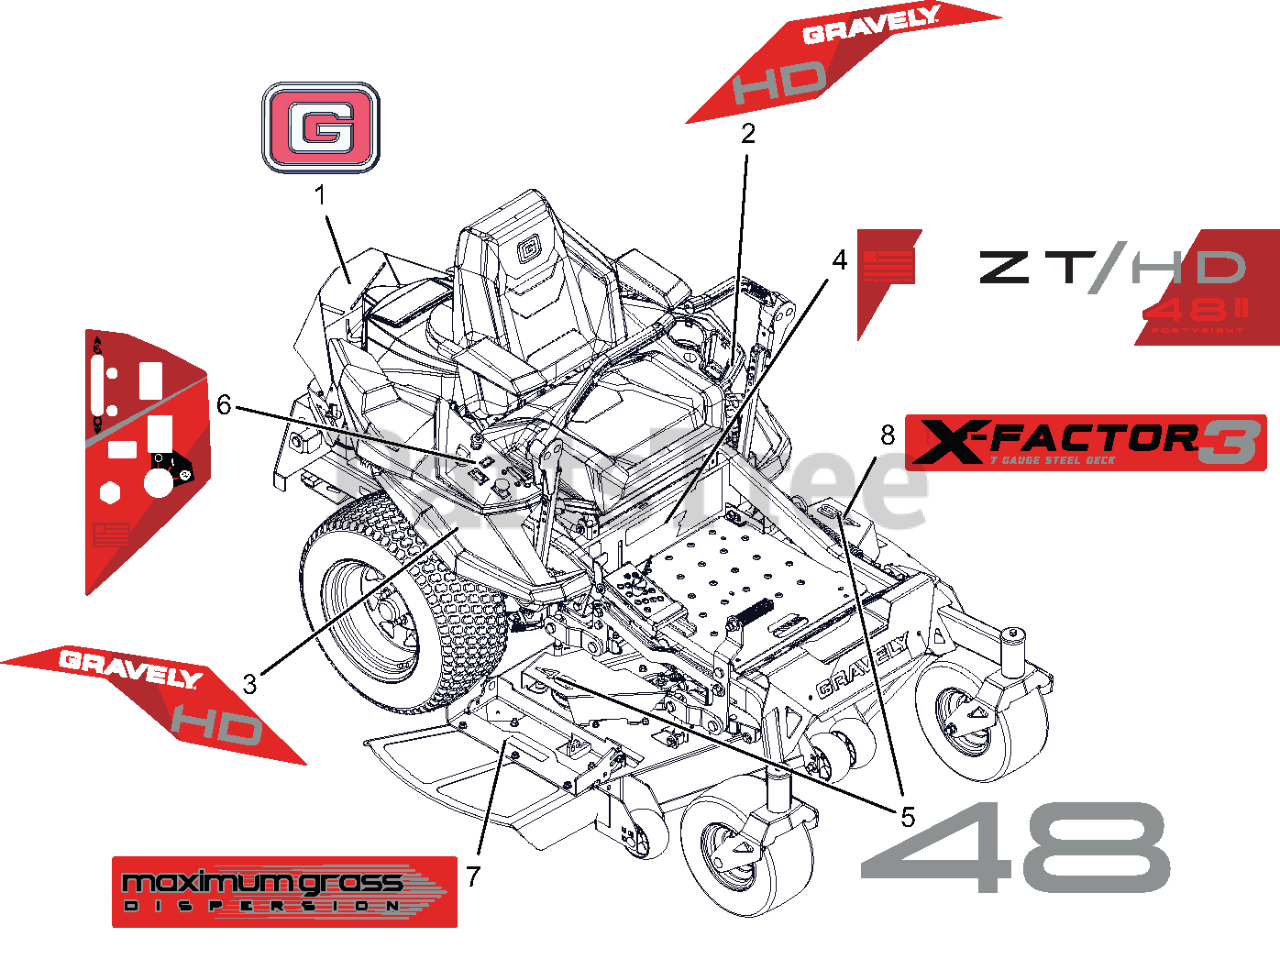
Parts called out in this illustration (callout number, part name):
1	DECAL, GRAVELY BRAND
2	DECAL, FENDER LH - HD
3	DECAL, FENDER RH - HD
4	DECAL, ZT/HD - 48
5	DECAL, DECK - 48
6	DECAL, CONTROL PANEL
7	DECAL, DECK - MAX GRASS
8	DECAL, DECK - X-FACTOR 3 7 GAUGE
